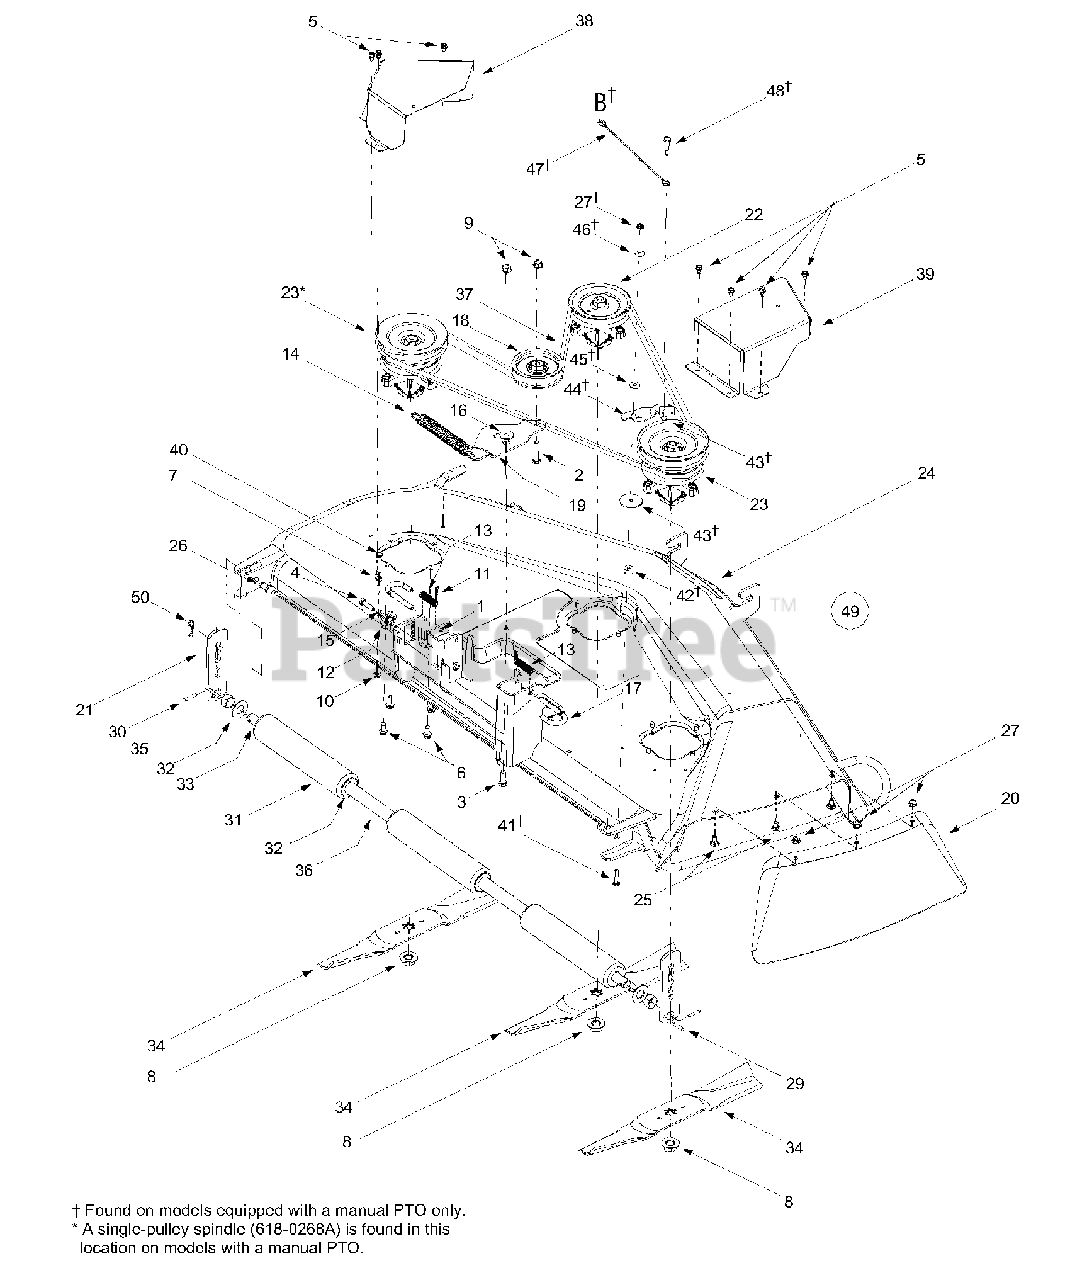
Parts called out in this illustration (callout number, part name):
1	Carriage Screw, 1/4-20 x .5
2	Hex Cap Screw, 3/8-16 x 1.75
3	Hex Cap Screw, 3/8-16 x 1.0
4	Hex Cap Screw, 5/16-18 x 1.25
5	Self Tapping Screw,1/4-20 x .5
6	Self Tapping Screw, 5/16-18 x .75
7	Center Lock Nut, 1/4-20
8	Hex Flange Nut, 5/8-18
9	Flange Lock Nut, 3/8-16
10	Hex Flange Lock Nut, 1/4-20
11	Internal Cotter Pin, .072 x 1.12
12	Deck Adjustment Gear
13	Compression Spring, .406 x .531 x 1.75
14	Extension Spring, .91 x 7.33
15	Lock Washer, 5/16
16	Shoulder Spacer, .625 x .169
17	Deck Release Pin
18	Flat Idler Pulley, 3.5 OD
22	Center Spindle Assembly, 5 Dia.
23	Double Pulley Spindle Assembly
26	Clevis Pin, .50 Dia. x .78
27	Hex Flange Lock Nut, 5/16-18 (Grade 5)
29	Spring Pin, 1/4 Dia. x 1
30	Spring Pin, 3/16 x 1.25
31	Deck Roller
32	Flat Washer, .78 x 1.59 x .06
33	Deck Roller Shaft, .75 Dia. x 47.12
34	Blade, Star Center, 17.3
35	Spacer, .752 x 1.0 x .53
41	Hex Cap Screw, 5/16-18 x 1.5
42	Spacer, .34 x .87 x .44
43	Flat Washer, .34 x 2.5 x .10
44	Deck Brake Assembly
45	Shoulder Spacer
46	Bell Washer, .325 x .930 x .045
47	Bracket Cable, 12"
48	Shoulder Screw, .374 x 1.16
